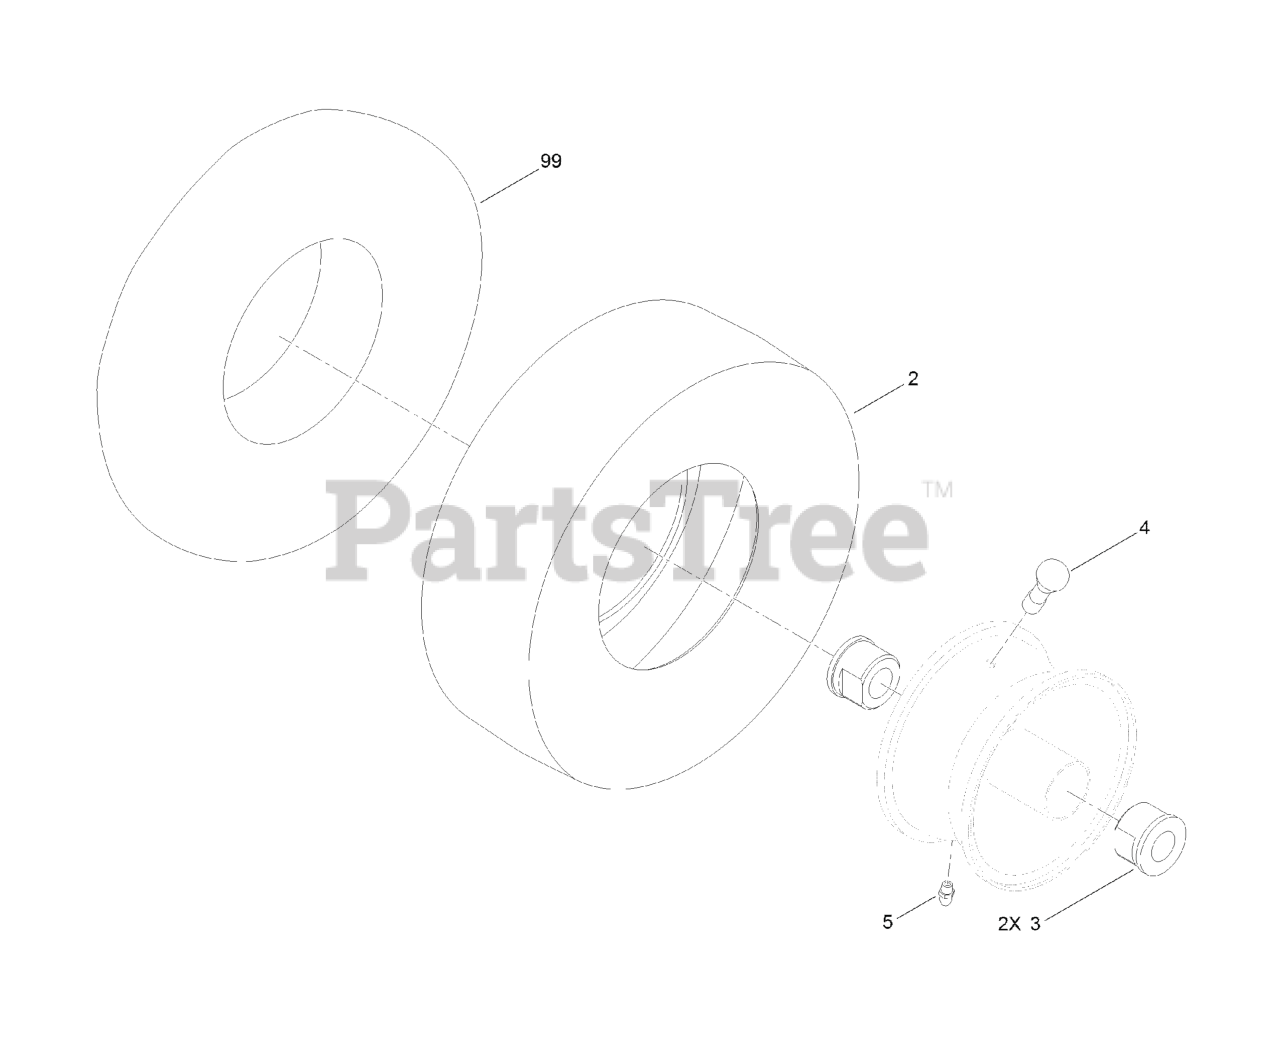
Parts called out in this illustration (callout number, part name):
3	BUSHING-FLANGE
4	Stem-Valve
5	FITTING-GREASE
99	TUBE-INNER
